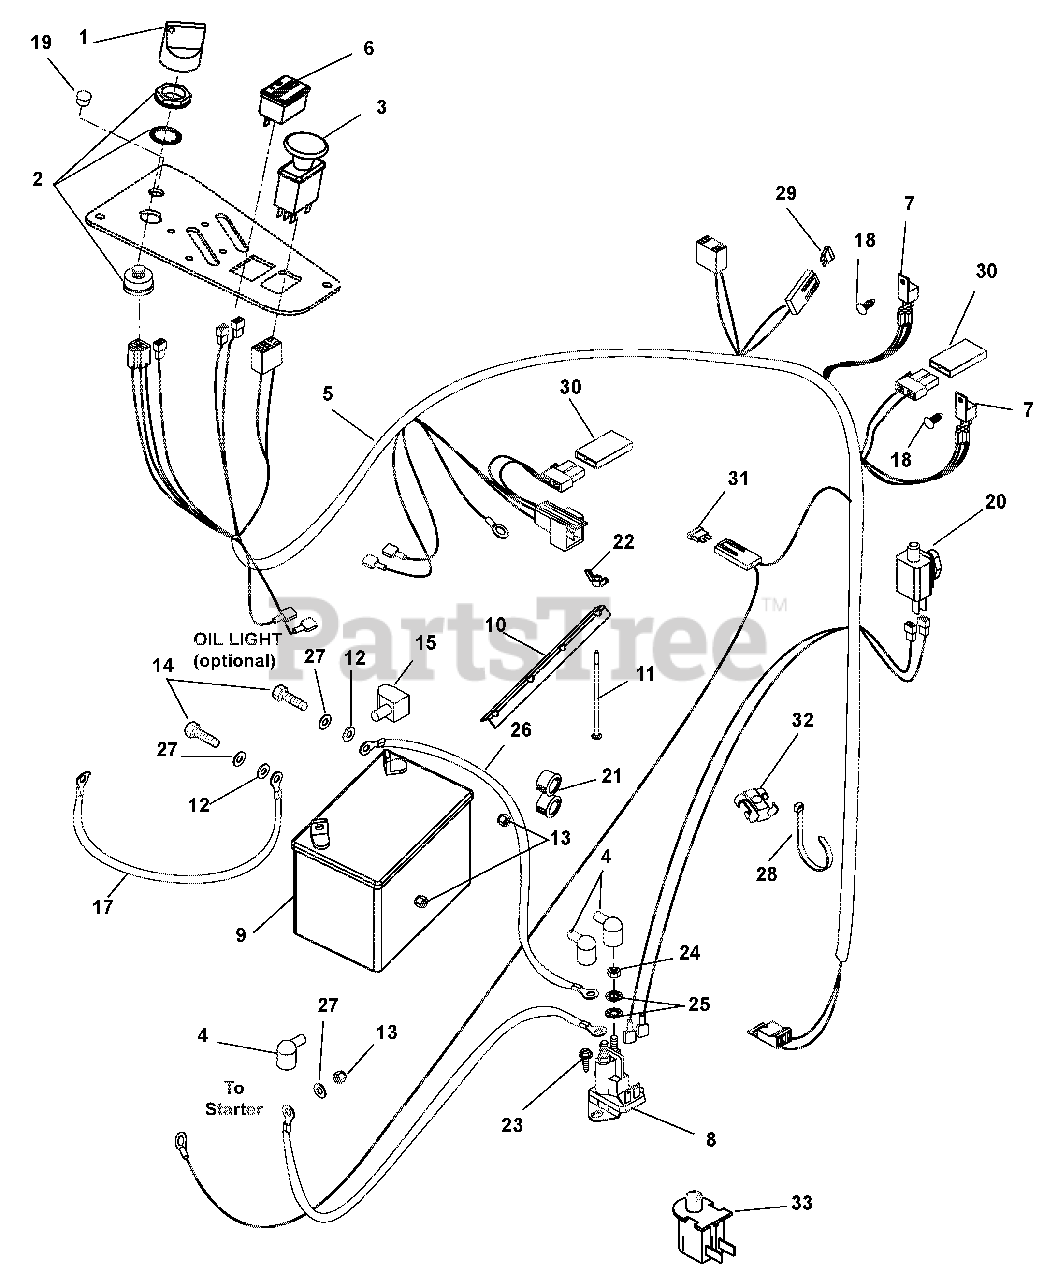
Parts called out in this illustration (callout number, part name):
1	Key with Shield
2	Switch, Ignition
3	Switch, Clutch
4	Boot, Eyelet Terminal
5	Harness Wire
6	Hour Meter with Maintenance
7	Relay, Sealed with Diode
8	Solenoid
10	Hold Down
11	Bolt, Round Head Square Neck .25-20 x 7.50
12	Washer, Flat Steel .281 x .620 x .065
13	Nut, Hex .25-20
14	Bolt, Hex .25-20 x .75 Grade 5
15	Insulator
16	Cable, Positive Battery 9.00"
17	Cable, Negative Battery
18	Rivet, .25 Nylon Panel
19	Plug, Hole .50 Diameter
20	Switch, Single Pole (N.O.) – Brake Switch
21	Bushing, Panel Snap .687 x .875 x .56
22	Nut, Locking Wing .25-20
23	Screw, Tapping .25-20 x .50 Hex Washer Head
24	Nut, Jam .31-24
25	Washer, Star Washer .31 x .078 Regular
26	Cable, Starter
27	Washer, Lock .25 x .062
28	Tie, Cable LG 5.50
29	Fuse 20 Amp
30	Diode, Connector Shell
31	Fuse, 25 Amp
32	Clip,T .31-.38
33	Switch, Snap Mounting N.O.
